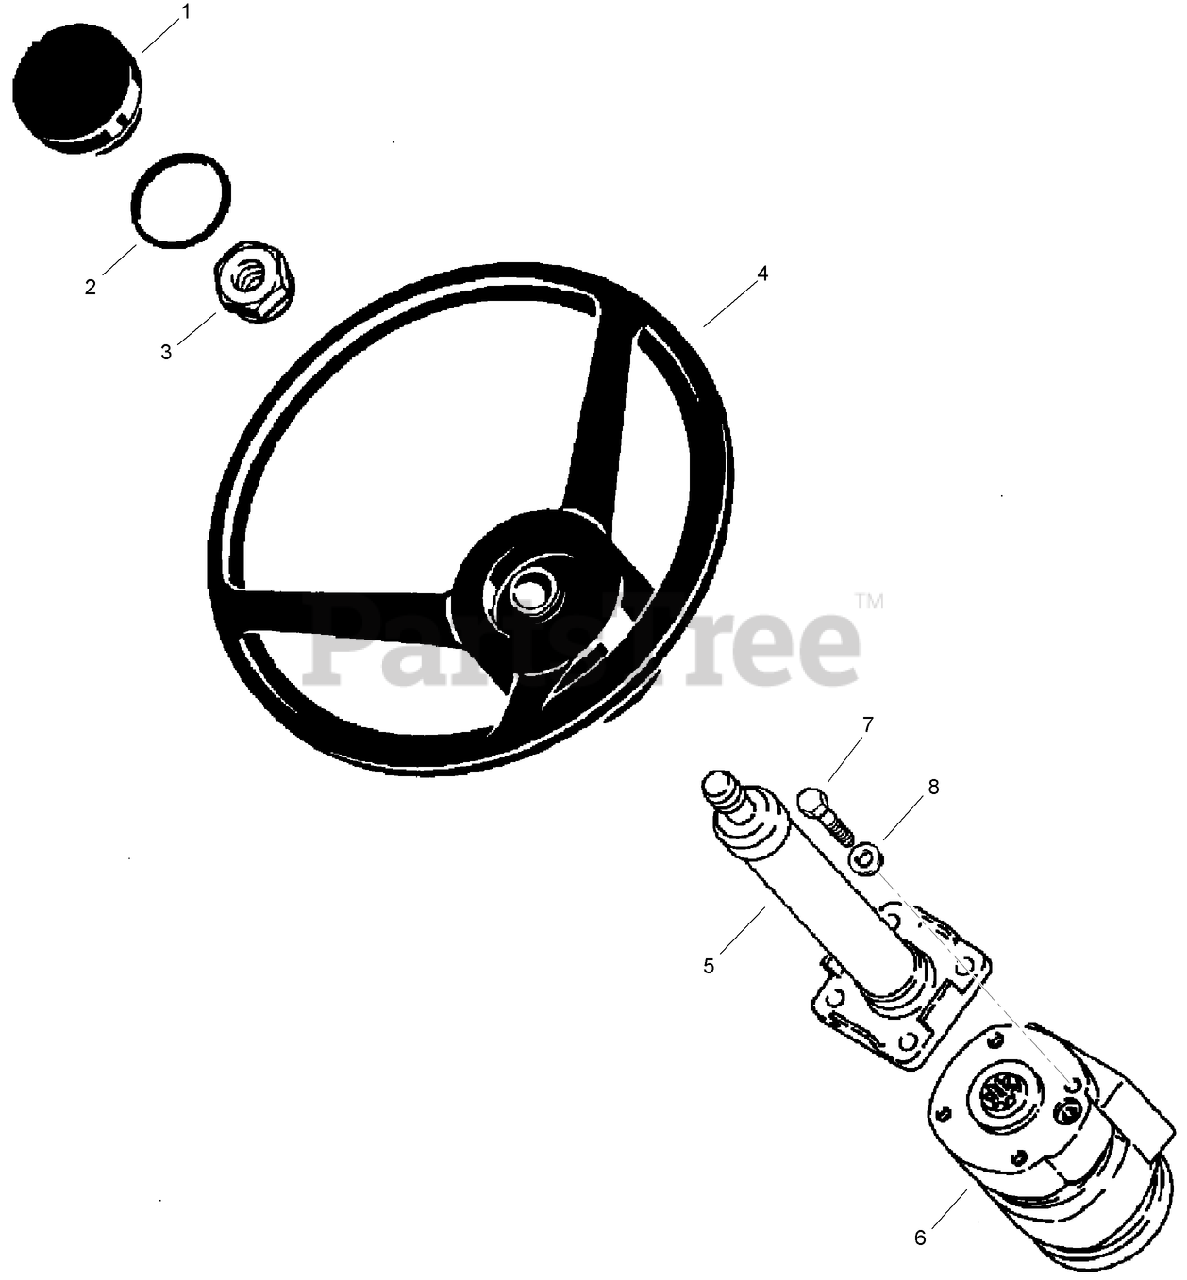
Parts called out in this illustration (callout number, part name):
1	CAP-STEERING WHEEL
4	WHEEL-STEERING
5	STEERING COLUMN ASM
6	HYD STEERING CONTROL VALVE ASM
7	BOLT-hex, 3/8 NC x 1-1/2 inch
8	WASHER-FLAT
